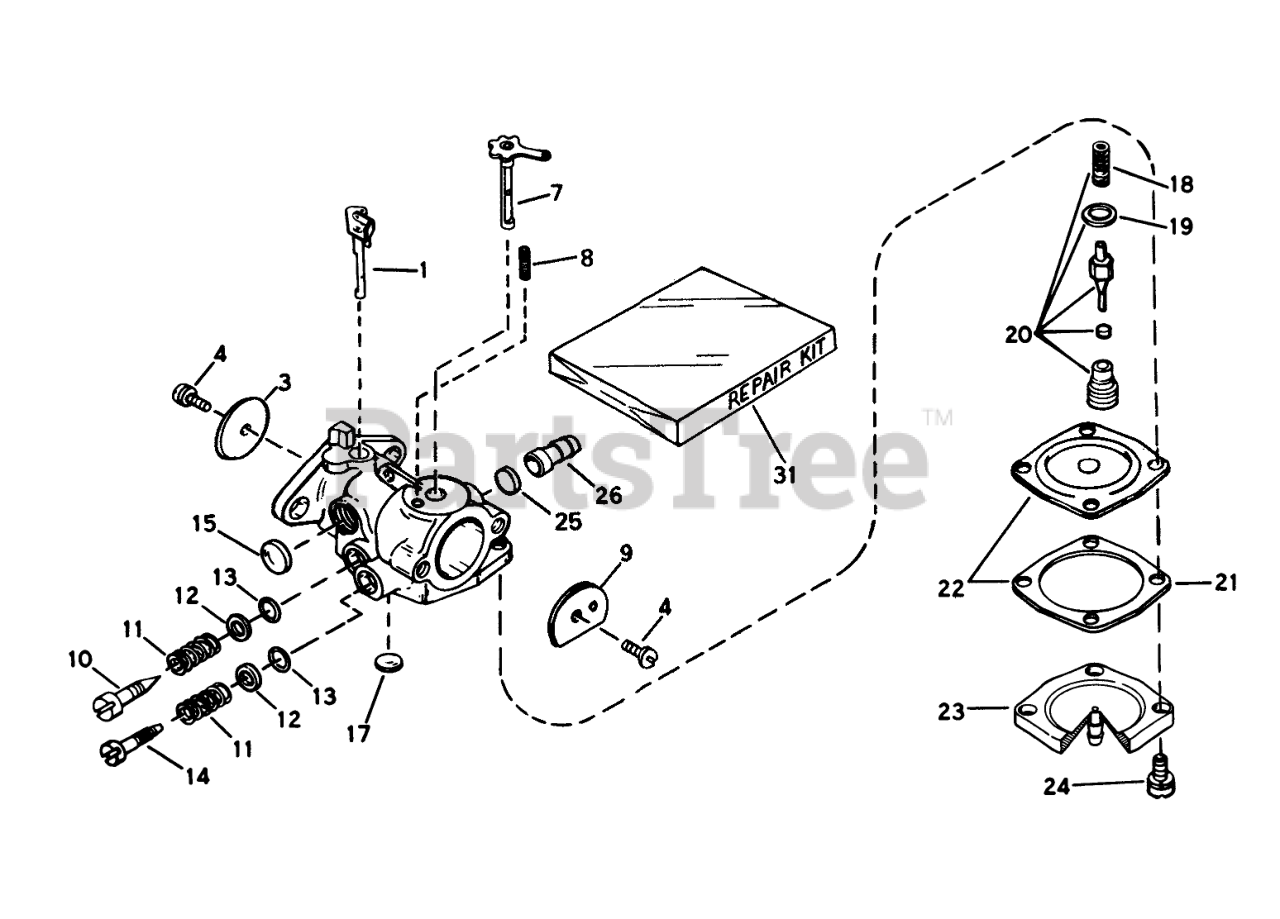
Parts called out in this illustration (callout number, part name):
1	Shaft/Lever-Throttle
3	Shutter-Throttle
4	Screw-Shutter
7	Shaft & Lever Assembly
8	Spring-Positioning, Choke
9	Shutter-Choke
10	Screw-Idle Adjustment
13	"O"Ring
14	Screw Main Adjustment
15	Plug-Welch, Idle Mixture Well
17	Plug-Welch, Idle Mixture Well
18	Spring-Valve
19	Gasket-Valve Seat
20	Inlet Needle, Seat, Spring & Gasket Assembly (Incl Ref. #18 & 19)
21	Gasket-Diaphragm
22	Diaphragm Assy. (Incl. Ref. #21)
23	Cover-Diaphragm
26	Fitting-Fuel
31	Kit-Repair
